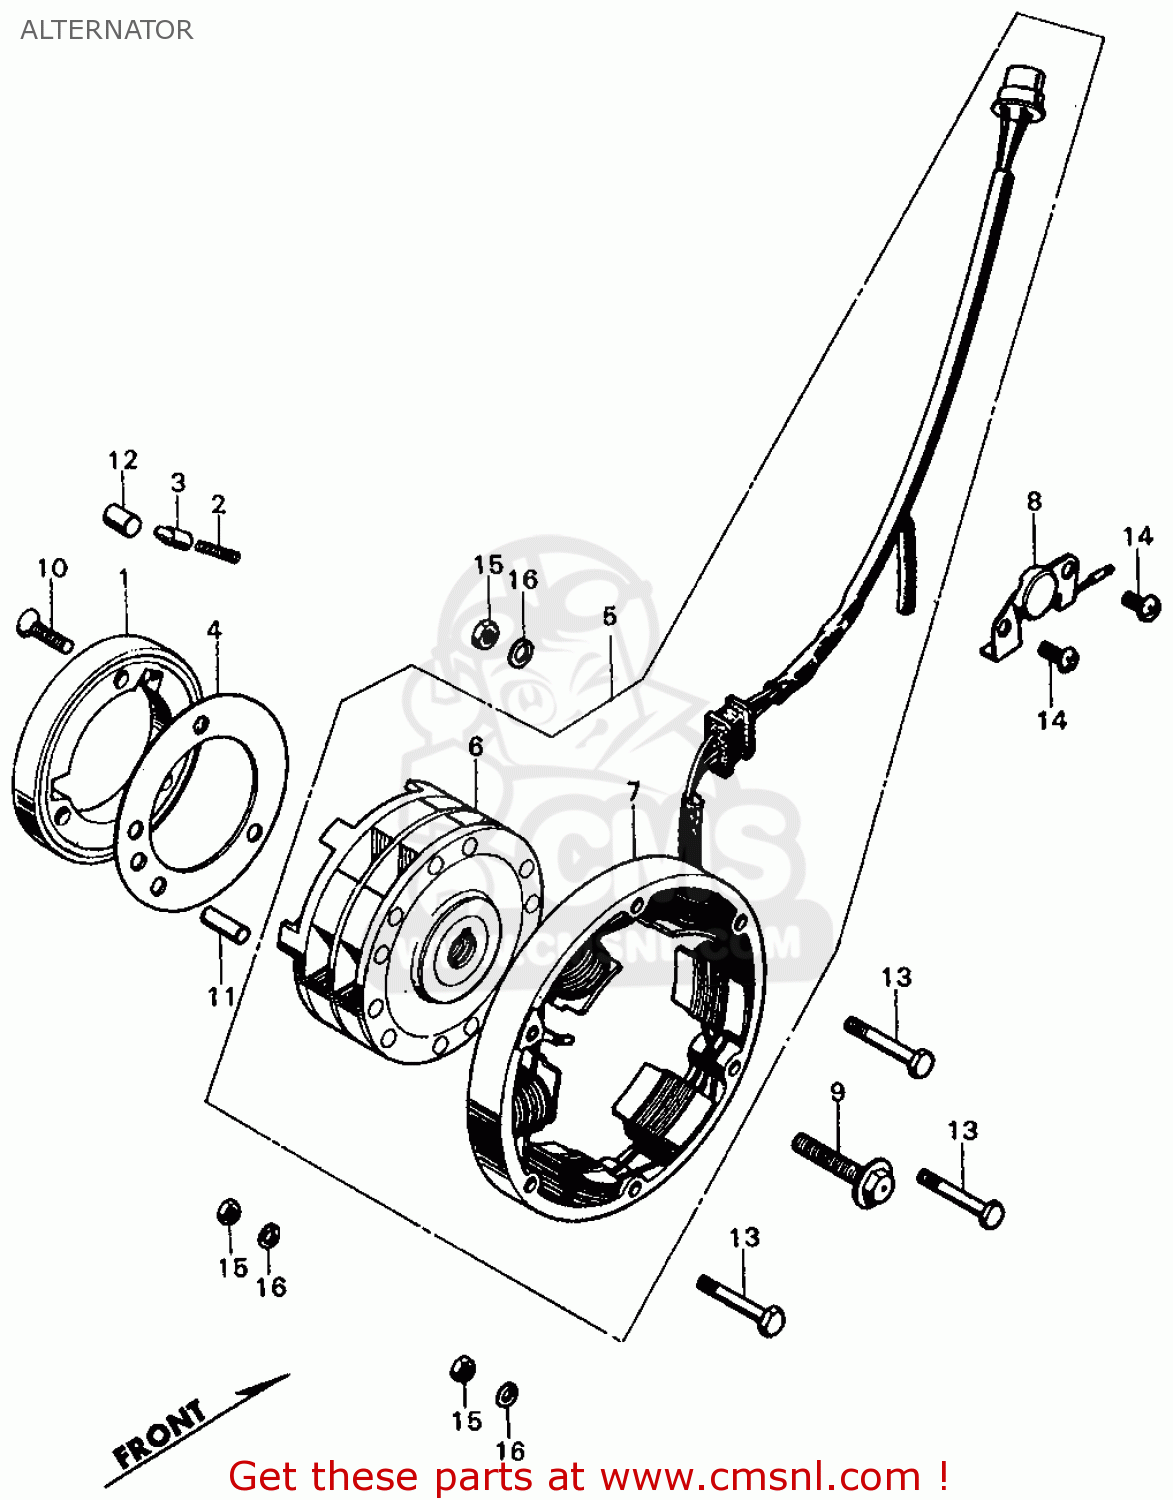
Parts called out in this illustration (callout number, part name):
1	OUTER,CLUTCH
2	SPRING, CLUTCH
3	CAP,SPRING
4	PLATE STARTING
5	A.C.GENERATOR
6	ROTOR,GENERATOR
7	STATOR,GENERATOR
8	SWITCH NEUTRAL
9	BOLT,ROTOR SET
10	SCREW,FLAT.6X25
11	PIN KNOCK 8X18
12	ROLLER,10.2X11.5
13	BOLT,HEX 6X36
14	SCREW,CROSS,6X10
15	NUT HEX 6MM
16	WASHER,SPRING,6MM
